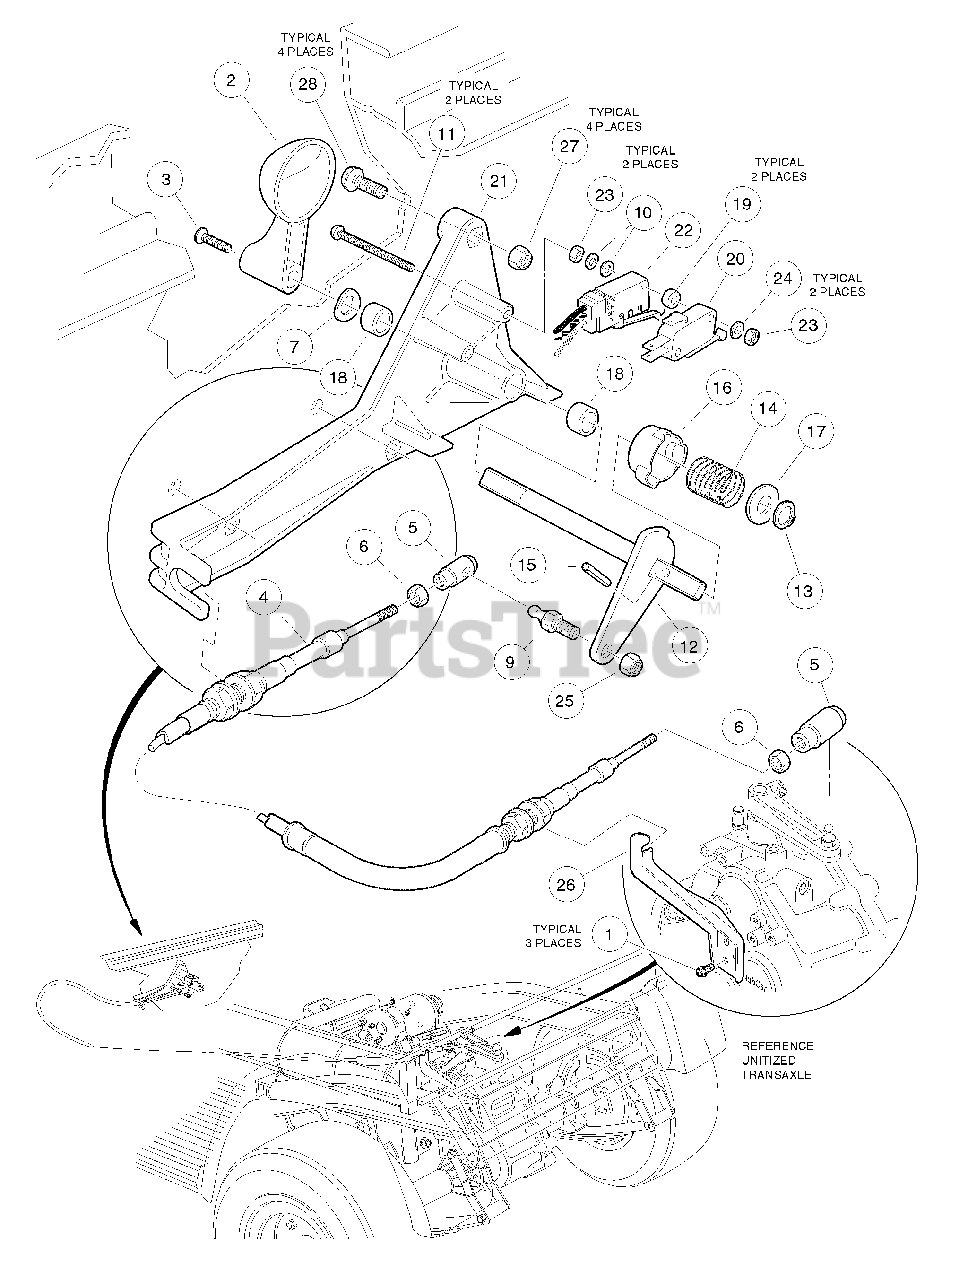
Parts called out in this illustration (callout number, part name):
1	Screw, 1/4 X 0.625 Hex-Head
2	Handle, FNR
3	Screw, #8-32 X 0.63 Machine
4	Cable, Shifter
5	Joint, #10-32 Ball
6	Nut, #10-32 Hex
7	Washer, Wave
8	Assembly, FNR Shifter
9	Stud, 1/4-28 X 0.560 Ball
10	Washer, #4 Flat
11	Screw, #4-40 Machine
12	FNR Bell Crank Weldment
13	Ring, 0.338" Internal Retaining
14	Spring, FNR Cam
15	Pin, 1/8 X 1/2 Roll
16	Neutral Lockout Cam Kit
17	Washer, 0.38" ID Delrin Flat
18	Bushing, Secondary Weight, Split
19	Washer, #4 Nylon Flat
20	Switch, Limit
21	FNR Shifter Base
22	Assembly, Switch, Limit
23	Nut, #4-40 Hex Machine
24	Lockwasher, #4 Helical Split
25	Locknut, 1/4-28 Nylon Insert
26	Bracket, Shifter
27	Locknut, 1/4-20 Nylon Insert
28	Screw, 1/4-20 X 0.75 Truss-Head Machine
